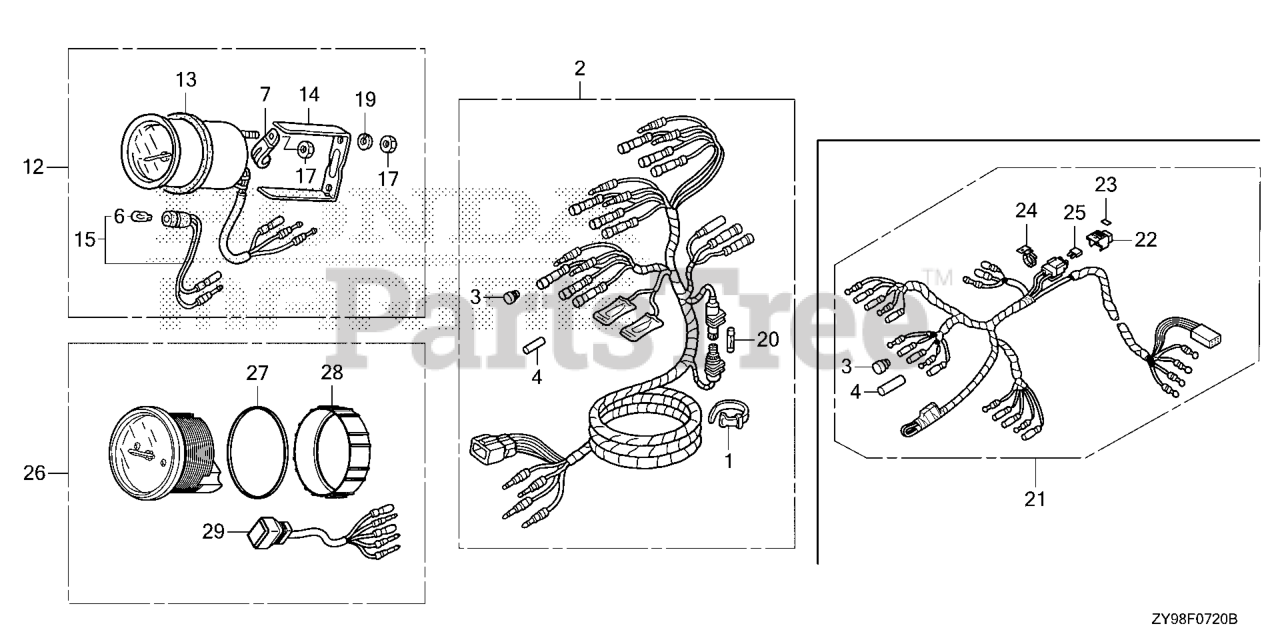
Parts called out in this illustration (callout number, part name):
1	BAND B1, CABLE Use up to Frame SN 1001879.
2	HARNESS ASSY., METER (A)
3	PLUG, CONNECTOR (INNER) (TROLLING CONTROL)
4	PLUG, CONNECTOR (OUTER) (ENGINE NO.)
5	BULB, WEDGE BASE (T10) (12V 1.7W) (STANLEY)
6	BULB, WEDGE BASE (12V1.7W) (TOSHIBA)
7	CLAMP
8	TACHOMETER ASSY.
9	GASKET
10	BRACKET (TO 1015209) (FROM 1015210)
11	SOCKET (TO 1015209) (FROM 1015210)
12	METER ASSY., TRIM
13	GASKET (TO 1015209) (FROM 1015210)
14	BRACKET (TO 1015209) (FROM 1015210)
15	SOCKET (TO 1015209) (FROM 1015210)
16	NUT, HEX. (5MM)
17	NUT, HEX. (4MM)
18	WASHER, SPRING (5MM)
19	WASHER, SPRING (4MM)
20	FUSE A (10A)
21	HARNESS ASSY., METER (A)
22	COVER ASSY., FUSE
23	LABEL, FUSE (10A)
24	HOLDER, CONNECTOR (128.6MM) (NATURAL)
25	FUSE, MINI (10A)
